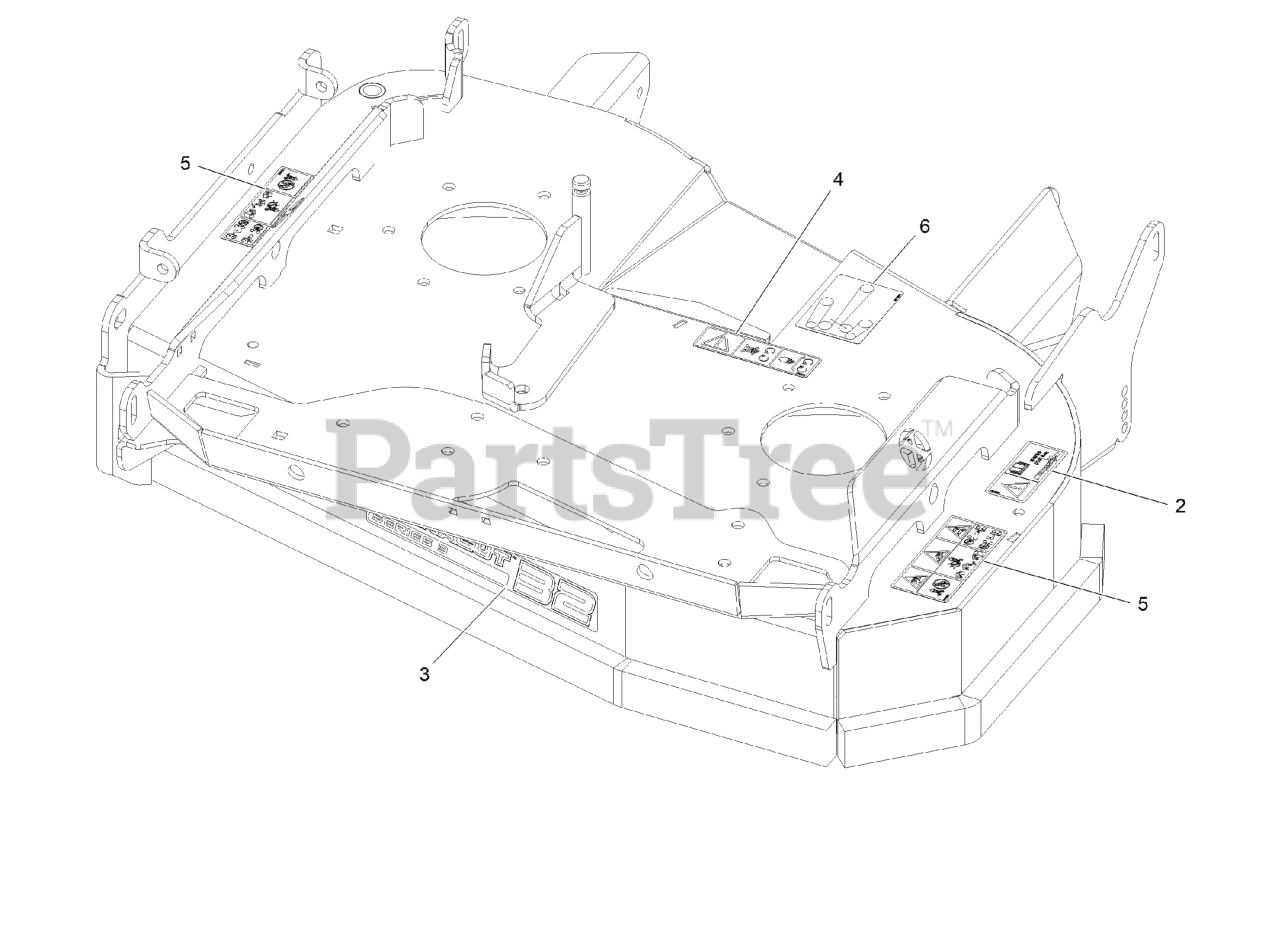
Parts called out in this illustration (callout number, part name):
2	DECAL-TORQUE, BOLT
3	DECAL-ULTRACUT 32-SERIES 3
4	DECAL-COVER, MISSING
5	DECAL-WARNING THROWN OBJECT
6	DECAL-BELT ROUTING
